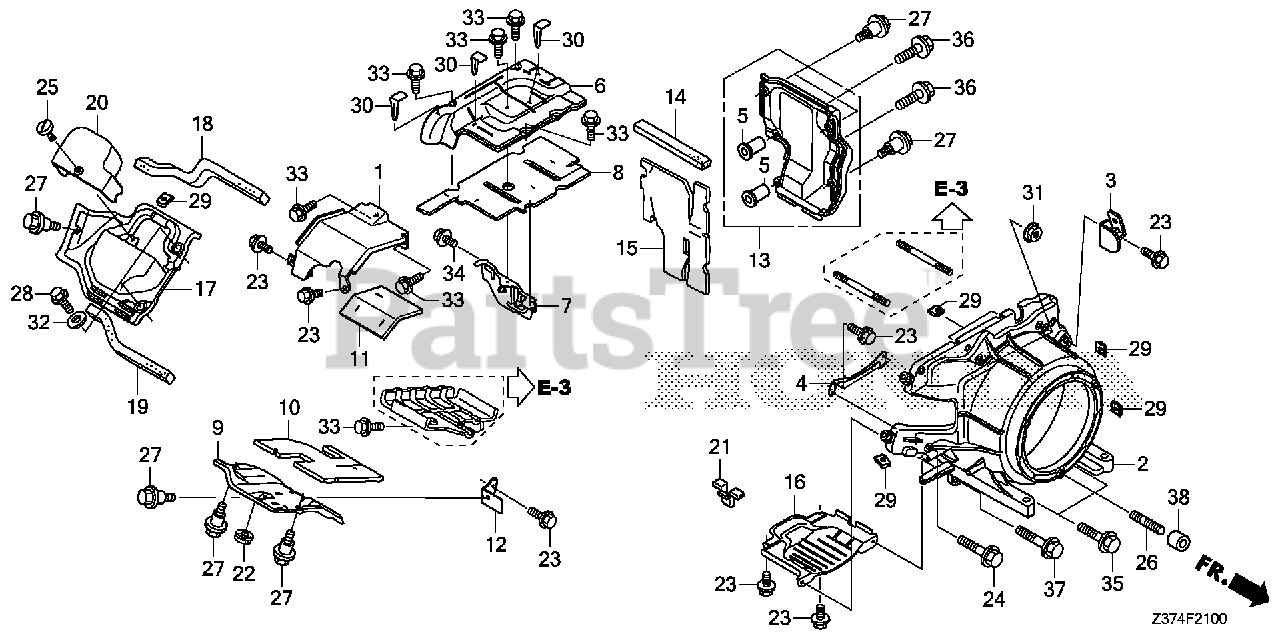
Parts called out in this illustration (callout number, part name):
1	SHROUD, HEAD
2	COVER, FAN
3	PLATE, R. SIDE
4	BRACKET, FAN COVER
5	COLLAR, FAN COVER (Honda Code 5580527). (N/A: SEE ASSEMBLY)
6	SHROUD (UPPER)
7	BRACKET, SHROUD (UPPER)
8	INSULATOR, SHROUD (UPPER)
9	SHROUD (LOWER)
10	INSULATOR, SHROUD (LOWER)
11	INSULATOR, HEAD SHROUD
12	BRACKET, SHROUD (LOWER)
13	SHROUD, R. SIDE
14	SEAL, R. SIDE COVER
15	INSULATOR, R. SIDE COVER
16	SHROUD (LOWER)
17	SHROUD, HEAD COVER
18	SEAL, HEAD COVER SHROUD (UPPER)
19	SEAL, HEAD COVER SHROUD (LOWER)
20	COVER, PLUG
21	RUBBER, OIL CHECK
22	GROMMET, SPEAKER PANEL
23	BOLT, FLANGE (6X12) (CT200)
24	BOLT, FLANGE (6X23)
25	SCREW, SPECIAL (6X16)
26	BOLT, STUD (6X20) (CT200)
27	BOLT, SPECIAL (6MM)
28	BOLT, FLANGE (6X12) (CT200)
29	NUT, SPRING (6MM)
30	CLIP, INSULATOR BIND (A)
31	NUT, FLANGE (6MM)
32	WASHER, PLAIN (6MM)
33	BOLT, FLANGE (6X12) Use from Engine SN 2086984.
34	BOLT, FLANGE (6X12)
35	BOLT, FLANGE (6X20)
36	BOLT, FLANGE (6X22)
37	BOLT, FLANGE (6X30)
38	COLLAR (6.6X13.8X10)
